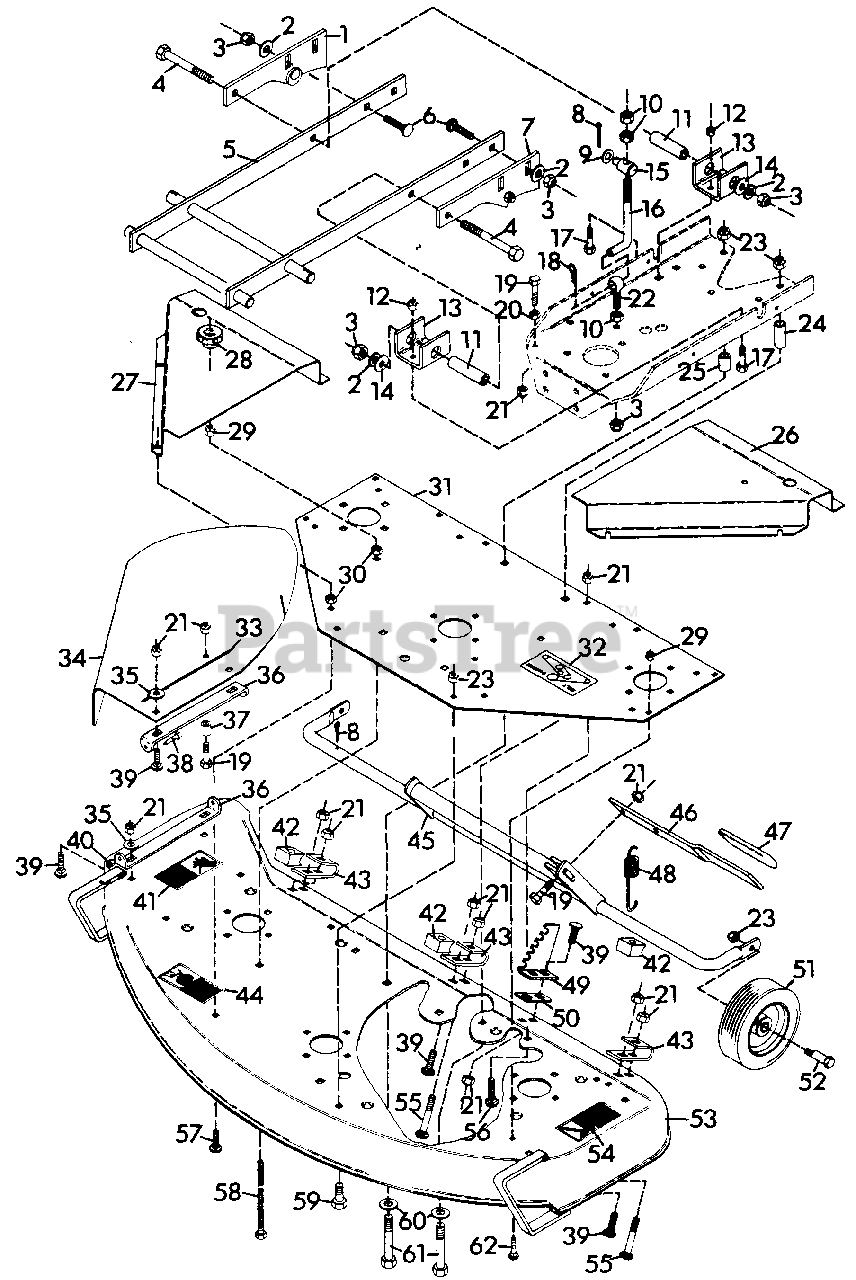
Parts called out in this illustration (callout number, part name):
1	Weldment, Deck Leveling R.H.
2	Washer, Flat .531x1.250x.100
3	Nut, Lock 1/2-13
4	Bolt, Hex 1/2-13x3.25
5	Weldment, Pivot Arm
6	Bolt, Carriage 1/2-13x1.25
7	Weldment, Deck Leveling L.H.
8	Pin, Cotter .125x1.25
9	Washer, Flat .531x1.000x.063
10	Nut, Jam 1/2-13 Hex
11	Bushing, Pivot .510x.750x2.020
12	Nut, Lock 5/16-18
13	Support, Mower Pivot
14	Washer, Flat .813x1.37x.100
15	Pivot, Mower Lift
16	Rod, Lift
17	Bolt, Hex 5/16-18x.875
18	Pin, Cotter Hair
19	Bolt, Hex 3/8-16x1.50
20	Nut, Jam 3/8-16 Hex
21	Nut, Lock 3/8-16
22	Bolt, Eye
23	Nut, Lock 1/2-13
24	Spacer, .510x.840x2.43
25	Spacer
26	Cover, Pulley L.H.
27	Cover, Pulley R.H.
28	Knob
29	Nut, Lock 5/16-18
30	Nut, Jam 5/16-18 Hex
31	Plate, Support
32	Decal, Belt Installation
33	Stripe
34	Shield, Safety Extension
35	Washer, Flat .406x.812x.065
36	Bracket, Chute
37	Stop, Chute
38	Bolt, Hex 1/4-20x.875
39	Bolt, 3/8-16x1 Rd Hd Sq Nk
40	Nut, Lock 1/4-20
41	Decal, Danger Hand
42	Stop, Nylon
43	Bracket, Axle Support
44	Decal, Warning Eye
45	Weldment, Axle Pivot
46	Lever, Height of Cut
47	Grip, Handle
48	Spring, 40 and 50 Inch Mower
49	Bracket, Height Adjust
50	Shim, Mower Ht. Adj. Bkt.
51	Wheel, Gauge
52	Bolt, Eccentric
53	Weldment, 50" Mower Deck
54	Decal, Danger Foot
55	Bolt, 3/8-16x2 Rd Hd Sq Nk
56	Bolt, Carriage 3/8-16x.75
57	Bolt, Carriage 5/16-18x1.00
58	Bolt, Hex 5/16-18x3.50
59	Bolt, Hex 1/2-13x1.25
60	Washer, Flat .531x1.062x.095
61	Bolt, Hex 1/2-13x3.75
62	Bolt, Carriage 5/16-18x.75
